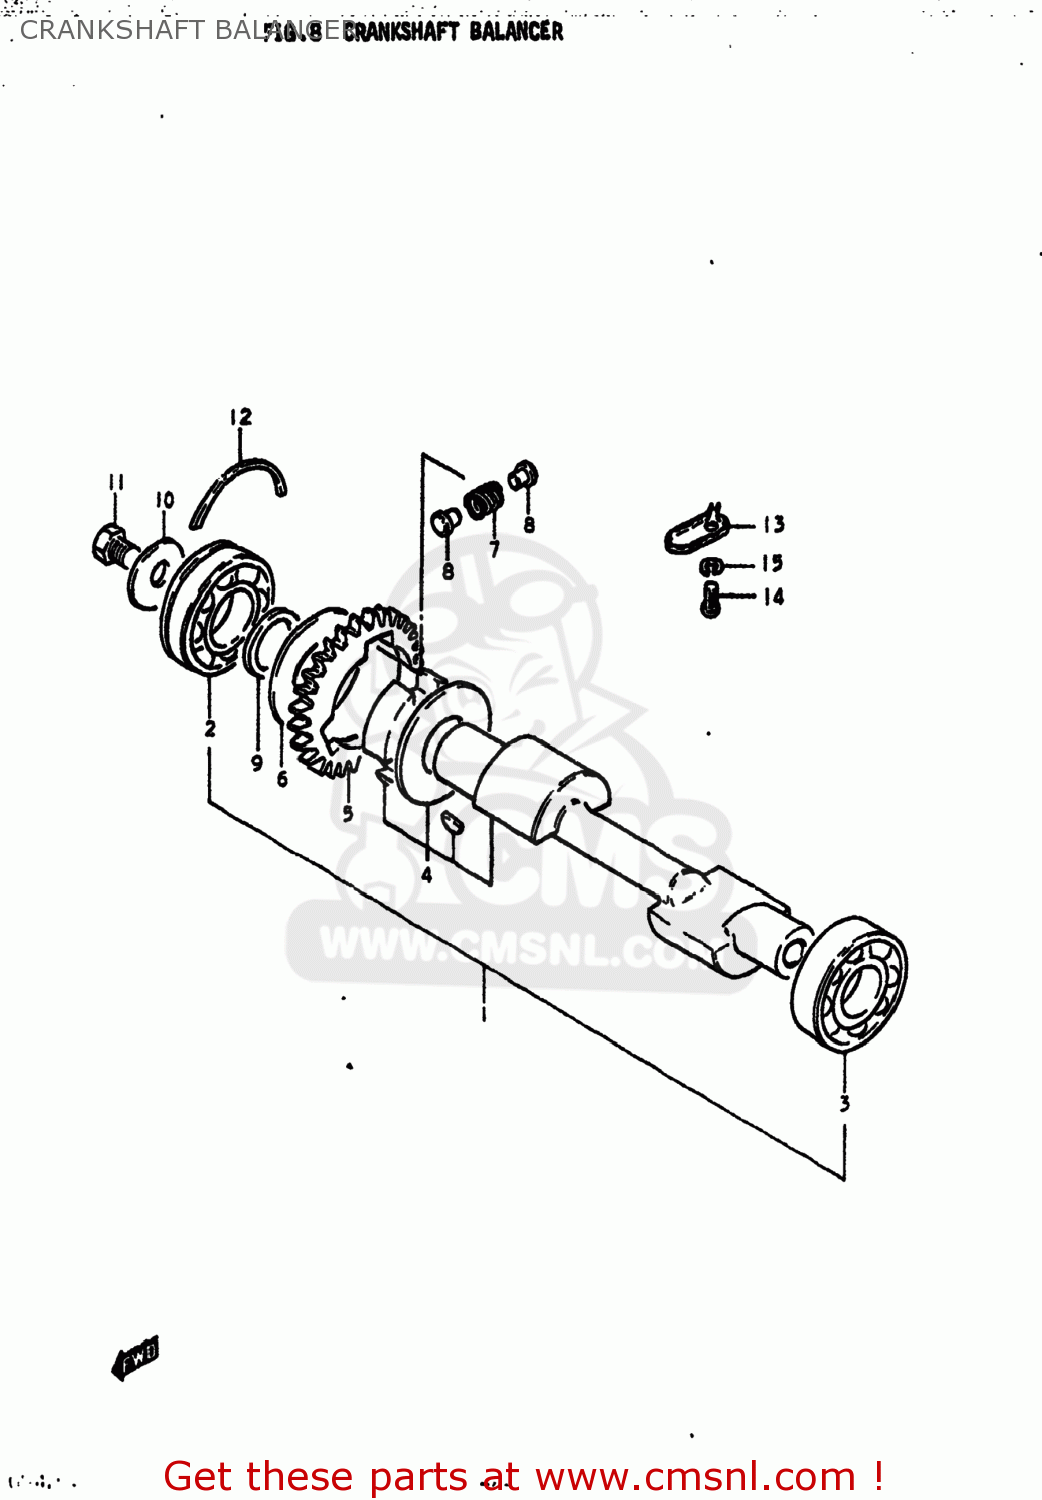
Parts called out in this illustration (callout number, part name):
1	BALANCER,CRANKSHAFT
2	BEARING
3	BEARING
4	CLUTCH SET,STARTER
5	GEAR,CRANK BALANCER DRIVE
6	WASHER (31X70X3)
7	SPRING
8	PIN
9	WASHER
10	WASHER
11	BOLT ,12X16
12	C RING
13	PLATE, OIL RESERVE
14	SCREW
15	LOCK WASHER
